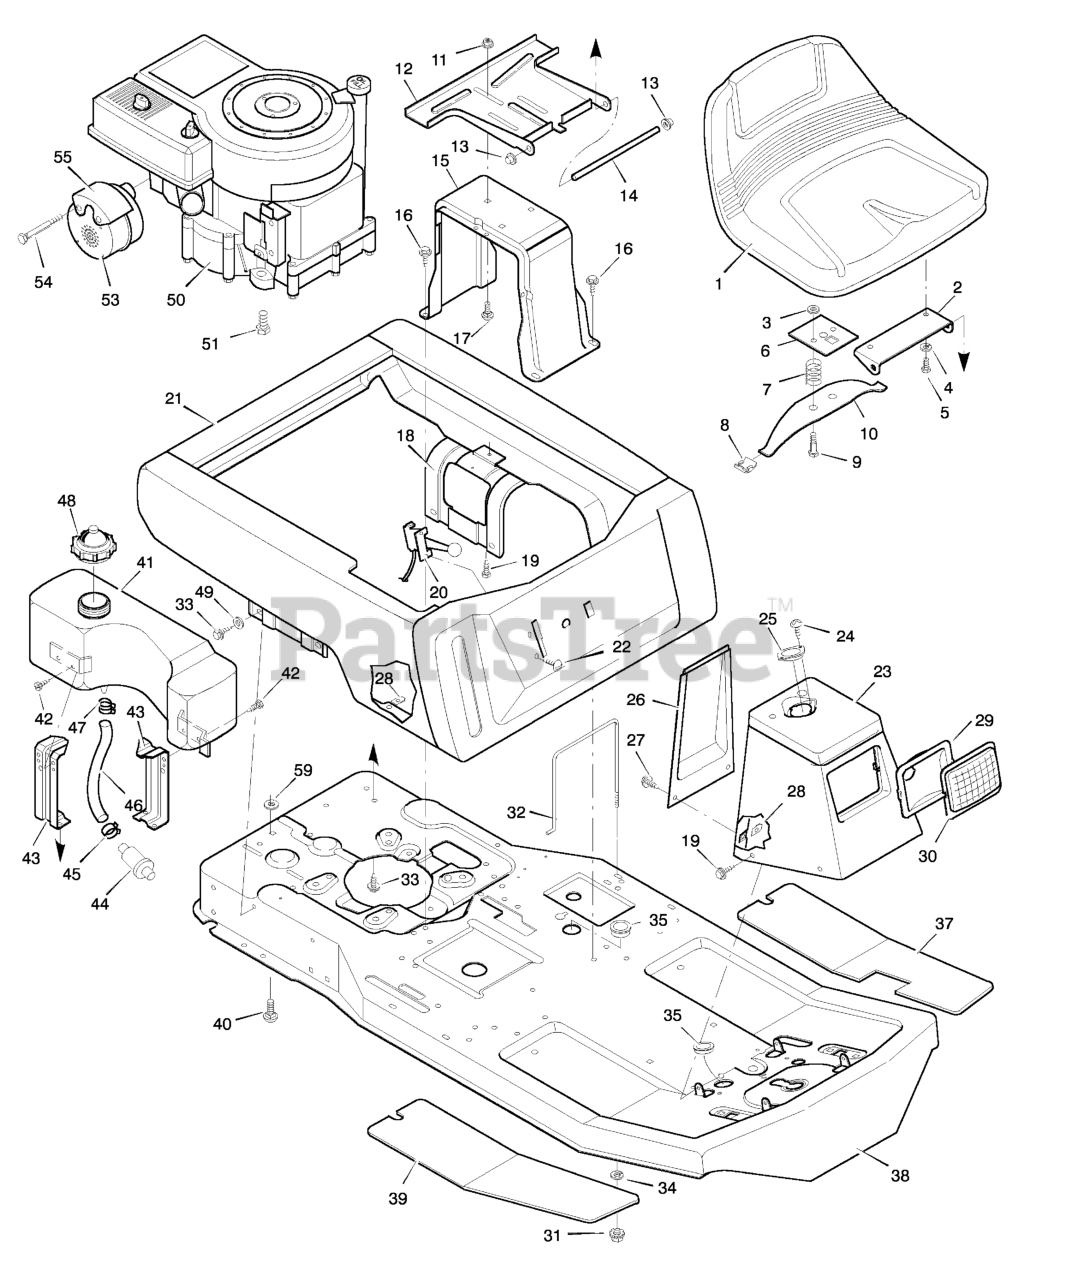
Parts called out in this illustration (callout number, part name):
2	Hinge, Seat
3	Retainer
4	Lockwasher
5	Bolt, Hex
6	Plate, Seat Switch
7	Spring, Compression
8	Glide, Seat Spring
9	Bolt, Shoulder
10	Spring, Seat
11	Locknut, Flange
12	Bracket, Seat Pivot
13	Cap, Push On
14	Rod, Seat Hinge
15	Support, Seat
17	Bolt, Carriage
18	Support, Body
20	Throttle Control
23	Console Assembly
25	Bearing, Steering Post
26	Console, Plate
29	Reflector
31	Locknut
32	Clamp, Battery
34	Washer
35	Grommet
37	Mat, Left
38	Frame Assembly
39	Mat, Right
40	Bolt, Carriage
41	Tank, Fuel
43	Bracket, Fuel Tank
44	Filter, Fuel
45	Clamp
46	Line, Fuel
47	Clamp
48	Cap, Fuel
49	Washer
50	Engine *
51	Bolt, Engine Mount
53	Muffler
55	Shield, Heat
59	Washer
